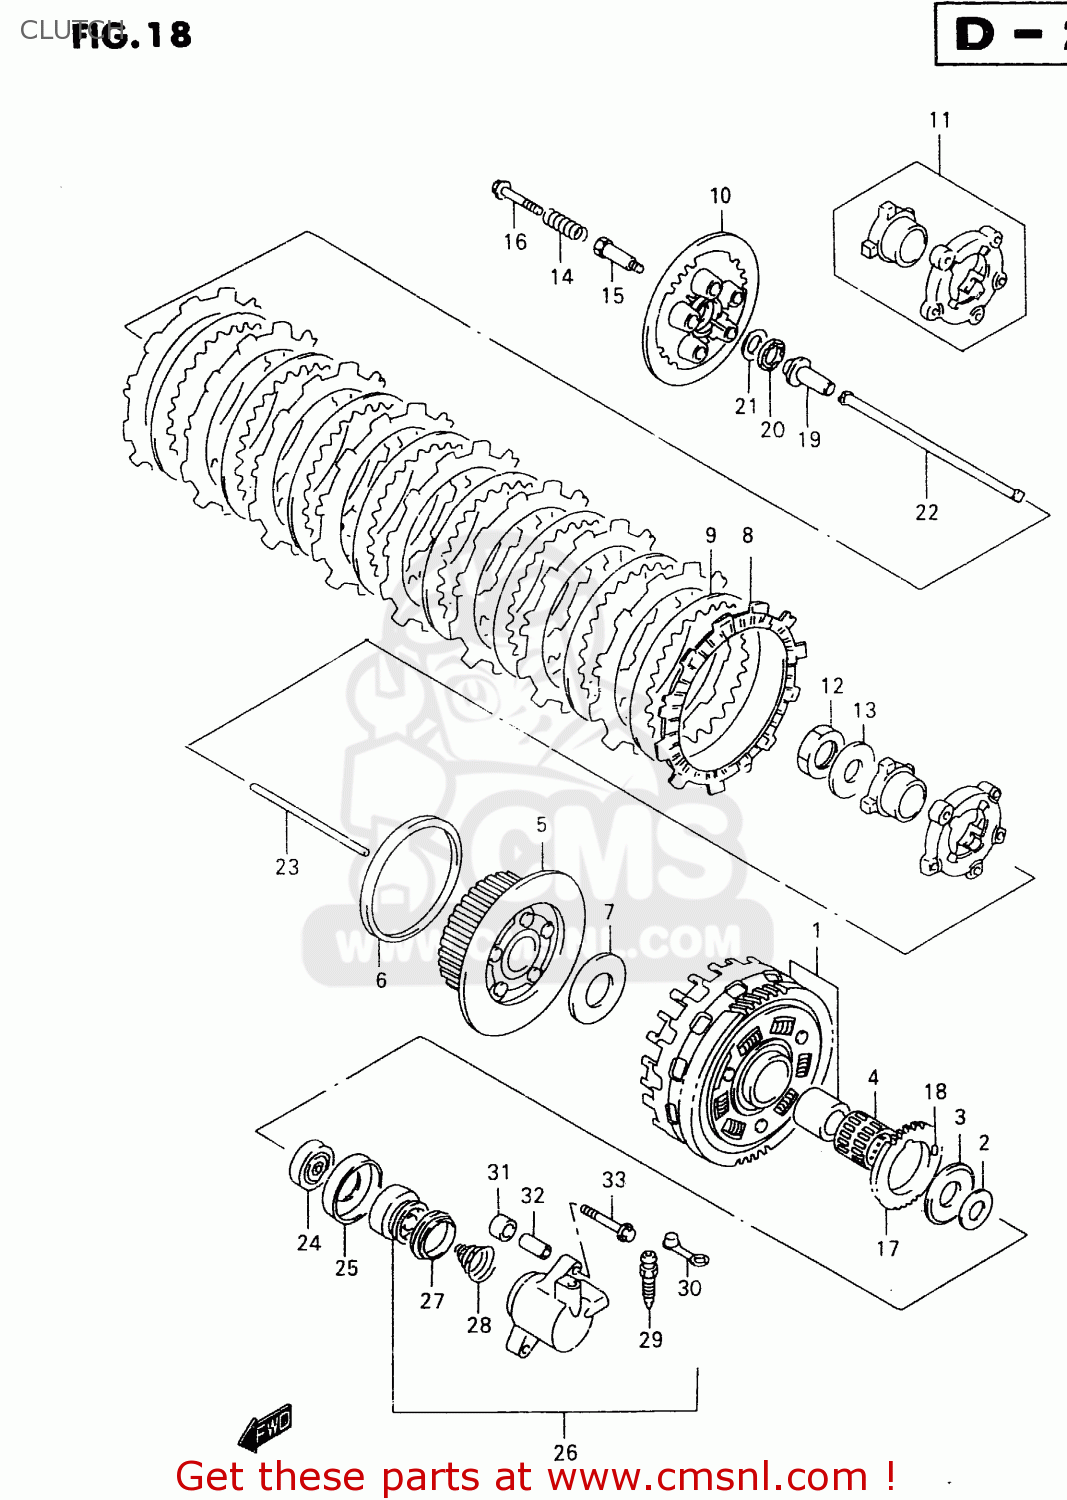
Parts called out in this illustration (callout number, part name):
1	GEAR ASSY,PRI DRIVEN
2	WASHER(25X38X2.5)
3	WASHER(25X54X2.5)
4	BEARING(35X40X35.8)
5	HUB,CLUTCH SLEEVE
6	WASHER
7	WASHER(25X50X2.5)
8	PLATE,CLUTCH DRIVE (NAS)
9	PLATE,CLUTCH DRIVEN NO.1 (NAS)
10	DISC,CLUTCH PRESSURE
11	CAM SET,CLUTCH
12	NUT
13	WASHER
14	SPRING,CLUTCH
15	BOLT,CLUTCH SPRING SUPPORT
16	BOLT,CLUTCH SPRING
17	GEAR,OIL PUMP DRIVE
18	PIN(6X6)
19	PIECE,CLUTCH PUSH
20	BEARING(15X28X2)
21	WASHER(15.5X28X1)
22	ROD,CLUTCH PUSH,R
23	ROD,CLUTCH PUSH,L
24	SEAL,OIL(6X34X11)
25	RETAINER,CL PUSH ROD OIL SEAL
26	CYLINDER,CLUTCH RELEASE
27	CUP
28	SPRING,CLUTCH CYLINDER
29	BLEEDER
30	CAP,BLEEDER
31	SPACER(9X16X11)
32	PIN(6.4X9X23)
33	BOLT
